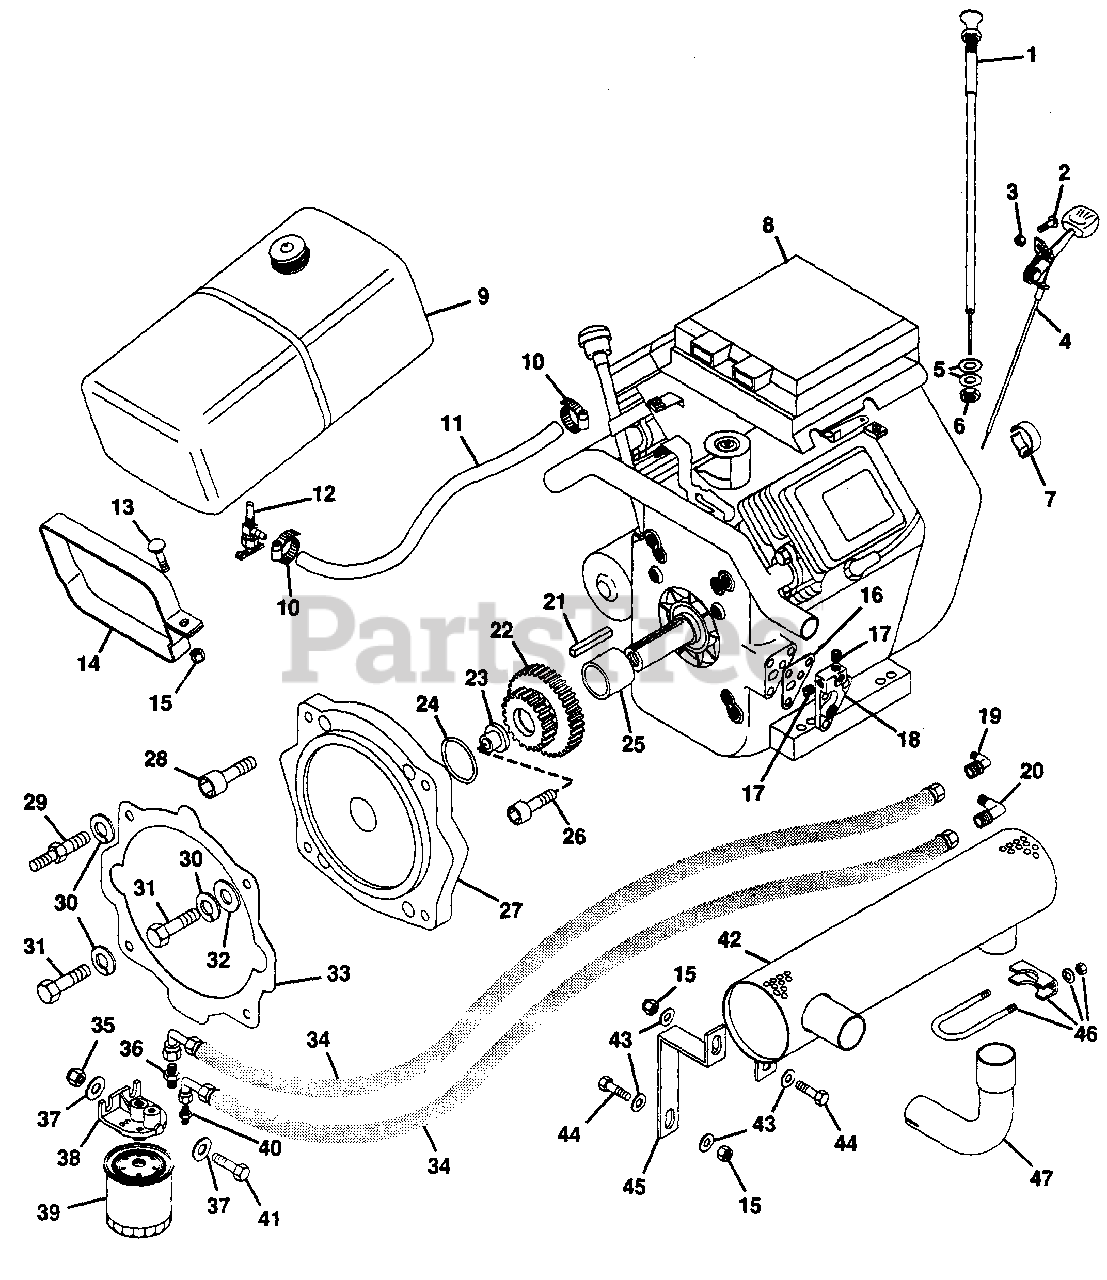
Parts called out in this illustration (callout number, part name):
1	LEVER, CHOKE CONTROL
2	SCREW, MACH. 10-24X.50 PHD
3	NUT, LOCK 10-24
4	LEVER, THROTTLE
5	WASHER, FLAT .406X.812X.065
6	NUT, HEX JAM 3/8-24
7	CLIP, CONDUIT
8	ENGINE, 16 H.P. B&S
9	TANK, GAS W/CAP
10	CLAMP, HOSE
11	LINE, FUEL
12	VALVE AND STRAINER
13	BOLT, 1/4-20X1.75 RD.HD.SQ. NK.
14	STRAP, FUEL TANK
15	NUT, LOCK 1/4-20
16	GASKET, OIL FILTER ADAPTOR
17	PLUG, 1/8-27 PIPE HSKT
18	ADAPTOR, REMOTE OIL FILTER
19	ADAPTER, 6-2-CTX-S
20	ADAPTER, 6CTX-S
21	KEY, SQUARE
22	GEAR, 10/12 DP 21/30 TEETH
23	PILOT, GEAR
24	O-RING
25	SPACER, GEAR
26	SCREW, 3/8-24X1.00 SHD
27	ADAPTOR, B&S ENGINE
28	SCREW, CAP 7/16-14X1.00 SHD
29	STUD
30	WASHER, LOCK 7/16 SP HEAVY
31	BOLT, HEX 7/16-14X1.25
32	WASHER, FLAT .469X.938X.065
33	GASKET, CHASSIS TO ADAPTOR
34	ASSEMBLY, HOSE
35	NUT, LOCK 5/16-18
36	FITTING, STRAIGHT PH 6FTX-S
37	WASHER, FLAT .344X.688X.065
38	ARM, BASE
39	FILTER, OIL
40	FITTING, STRAIGHT PH 6-2FTX-S
41	BOLT, HEX 5/16-18X1.25
42	MUFFLER, 16 H.P.
43	WASHER, FLAT .312X.734X.065
44	BOLT, HEX 1/4-20X1.00
45	BRACKET, EXHAUST
46	CLAMP, MUFFLER
47	ELBOW
